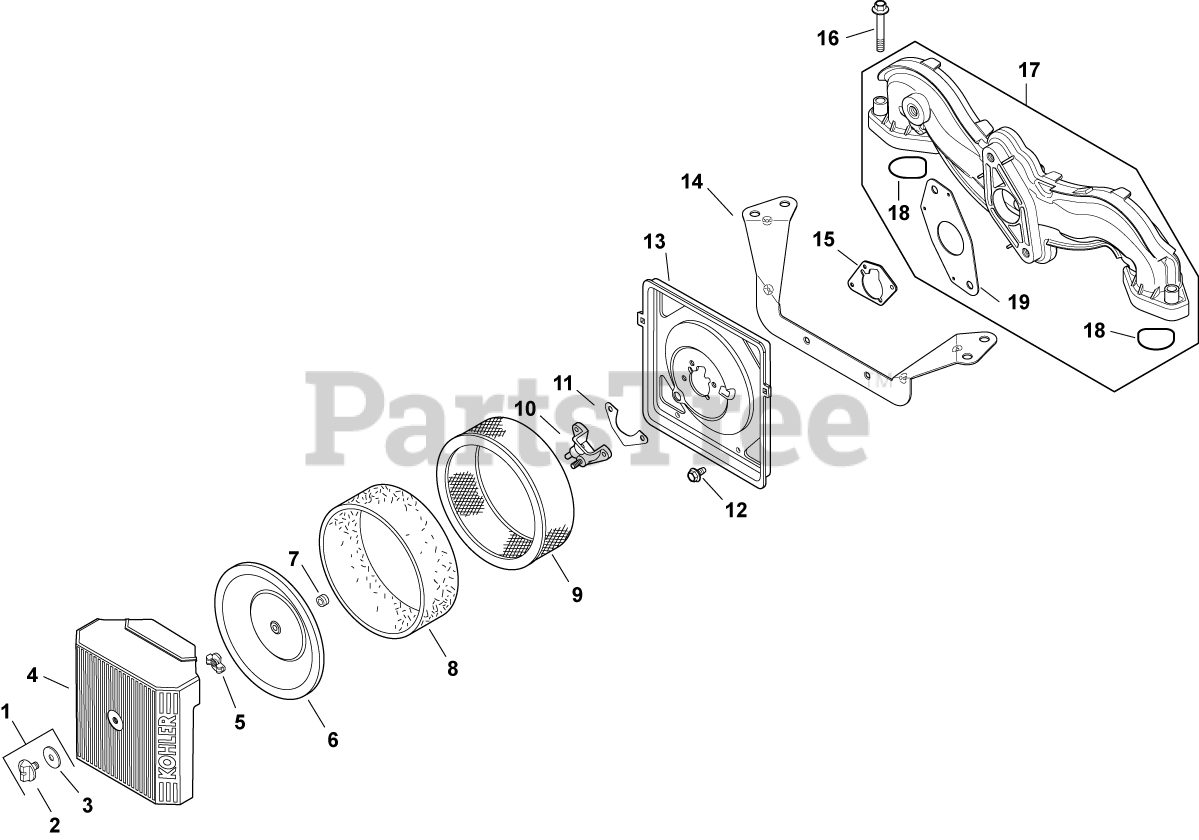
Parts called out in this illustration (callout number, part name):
1	KIT, KNOB W/SEAL
2	KNOB, COVER
4	COVER, AIR CLEANER
5	NUT, WING
6	COVER, INNER AIR CLEANER
7	SEAL, INNER AIR CLEANER
8	ELEMENT, PRECLEANER (LOW)
9	ELEMENT, AIR CLEANER - Also available Retail Packaged 47 883 03-S1 Air Filter Kit
10	CUP, SPIT-BACK W/STUD
11	GASKET, FUEL SPITBACK CUP
12	SCREW, FLG THD FRM M5X.8X10
13	BASE, AIR CLEANER-USE 24 094 87-S
14	BRACKET, AIR CLEANER BASE
15	GASKET, AIR CLEANER BASE
16	SCREW, FLG M6X1.0X40
17	MANIFOLD, INTAKE - PLASTIC-USE 24 164 91
18	O-RING, INTAKE PORT
19	GASKET, CARBURETOR
